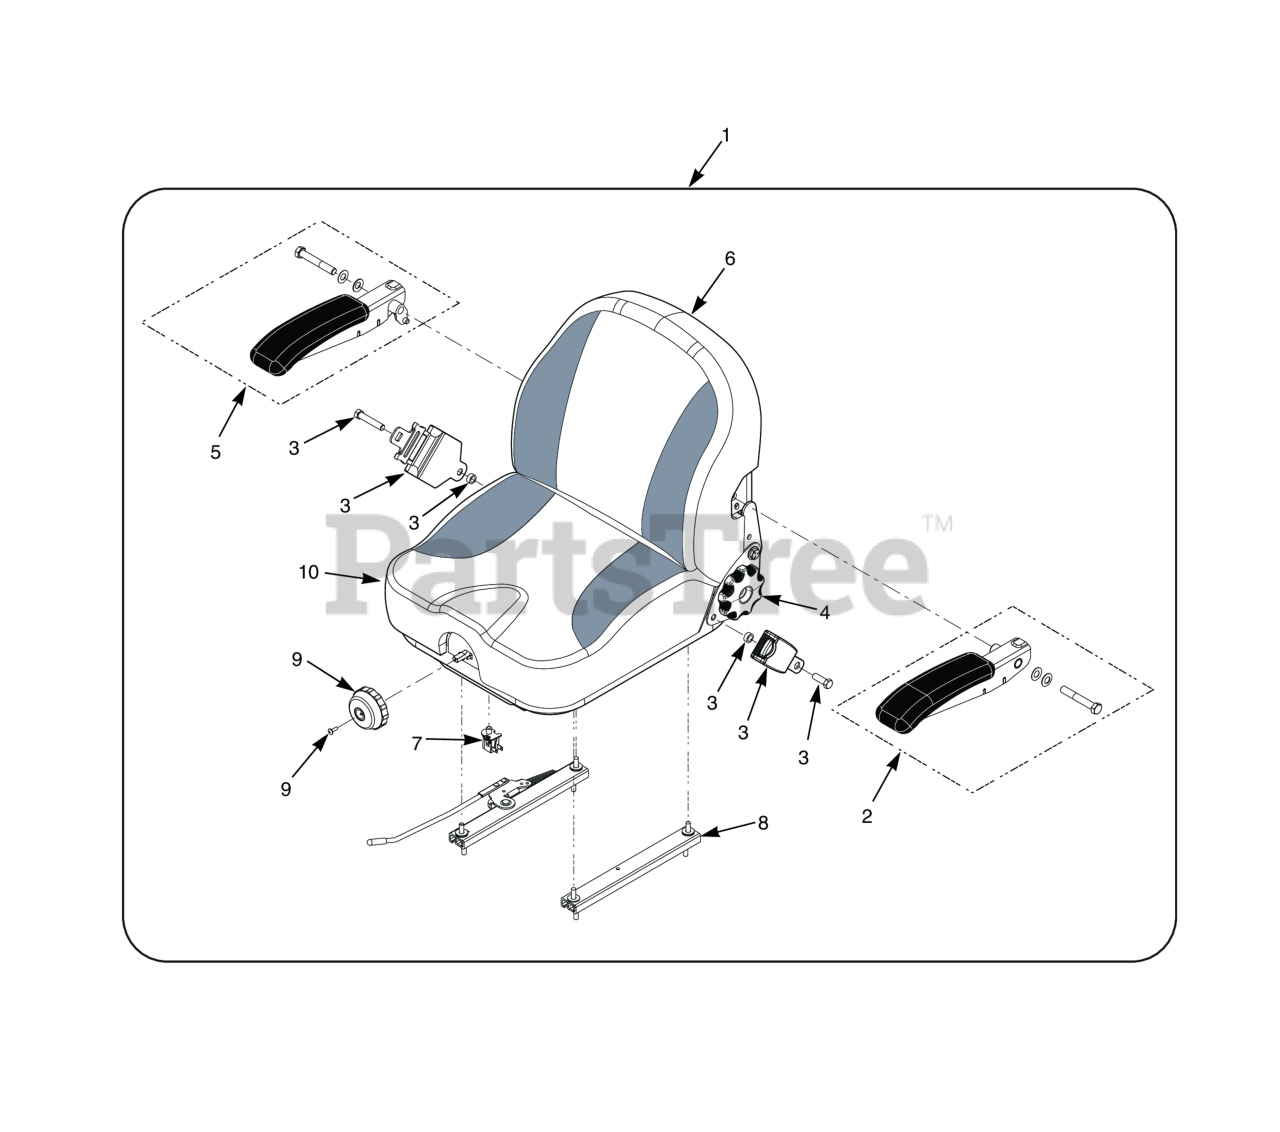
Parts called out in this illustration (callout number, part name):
1	Suspension Seat Assembly w/seat belt
2	Armrest Kit, LH
3	Seat Belt Kit (Suspension Seat)
4	Knob Kit, Recliner
5	Armrest Kit, RH
6	Cover, Back Cushion
7	Switch, Interlock, Normally Open
8	Track Kit
9	Knob Kit, Weight Adjust
10	Cover, Seat Cushion
